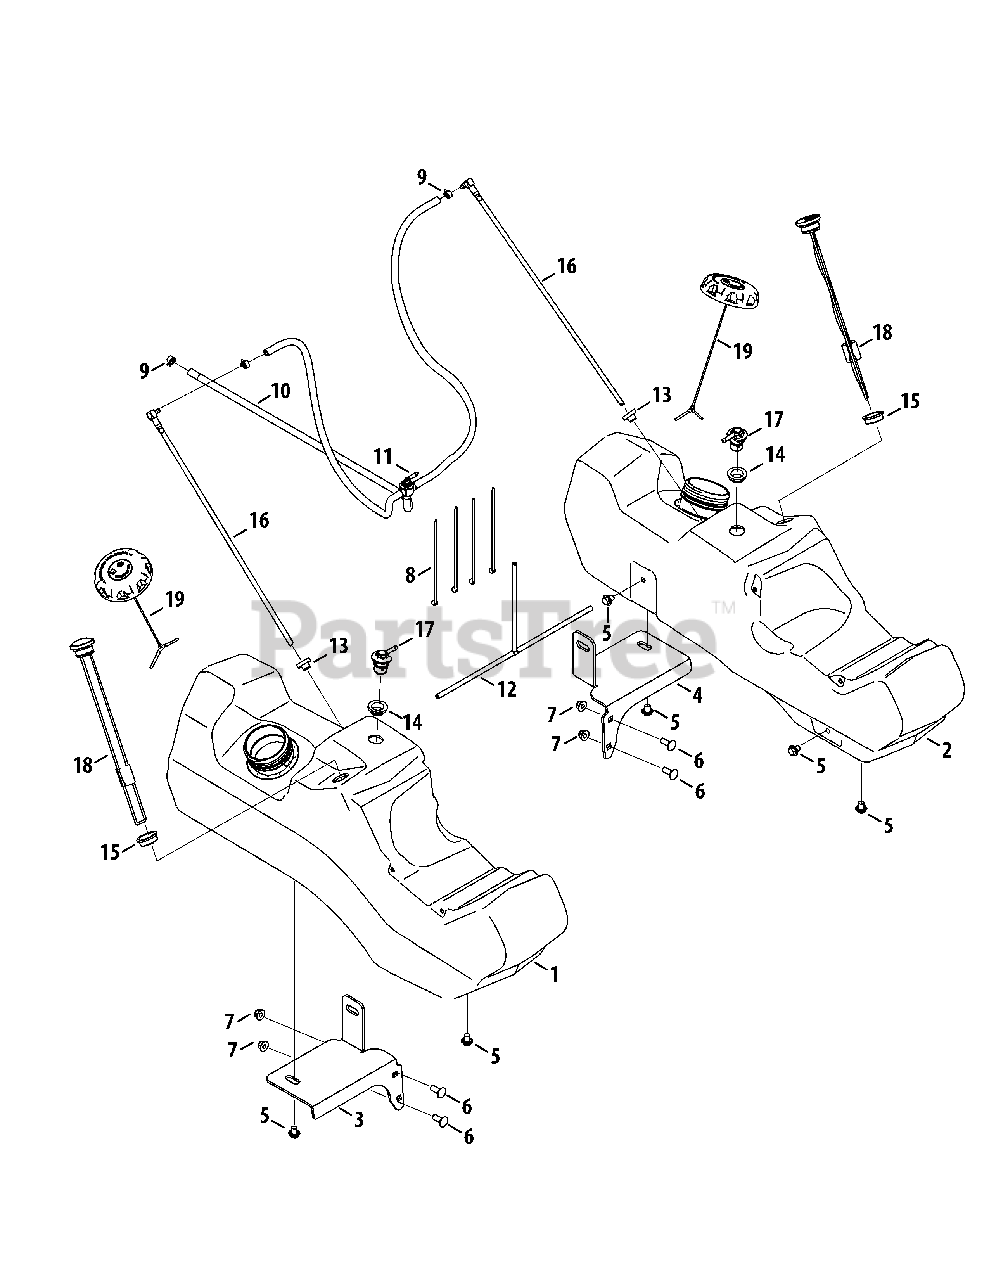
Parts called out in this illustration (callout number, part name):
1	Fuel Tank Assembly, RH
2	Fuel Tank Assembly, LH
3	Rear Fuel Bracket, RH
4	Rear Fuel Bracket, LH
5	Hex Cap Screw, 3/8-16 x .500
6	Carriage Bolt, 3/8-16 x .500
7	Nut, 3/8-16, Flangelock
8	Cable Tie
9	Hose Clamp, .500 Dia.
10	Fuel Hose., 1/4
11	Fuel Switch
12	Fuel Hose Assembly includes:
13	Grommet, Fuel Tank
14	Rubber Grommet
15	Grommet, 1.58 OD x 1.21 ID x .5
16	Fuel Pickup Valve
17	Fuel Rollover Valve
18	Fuel Gauge
